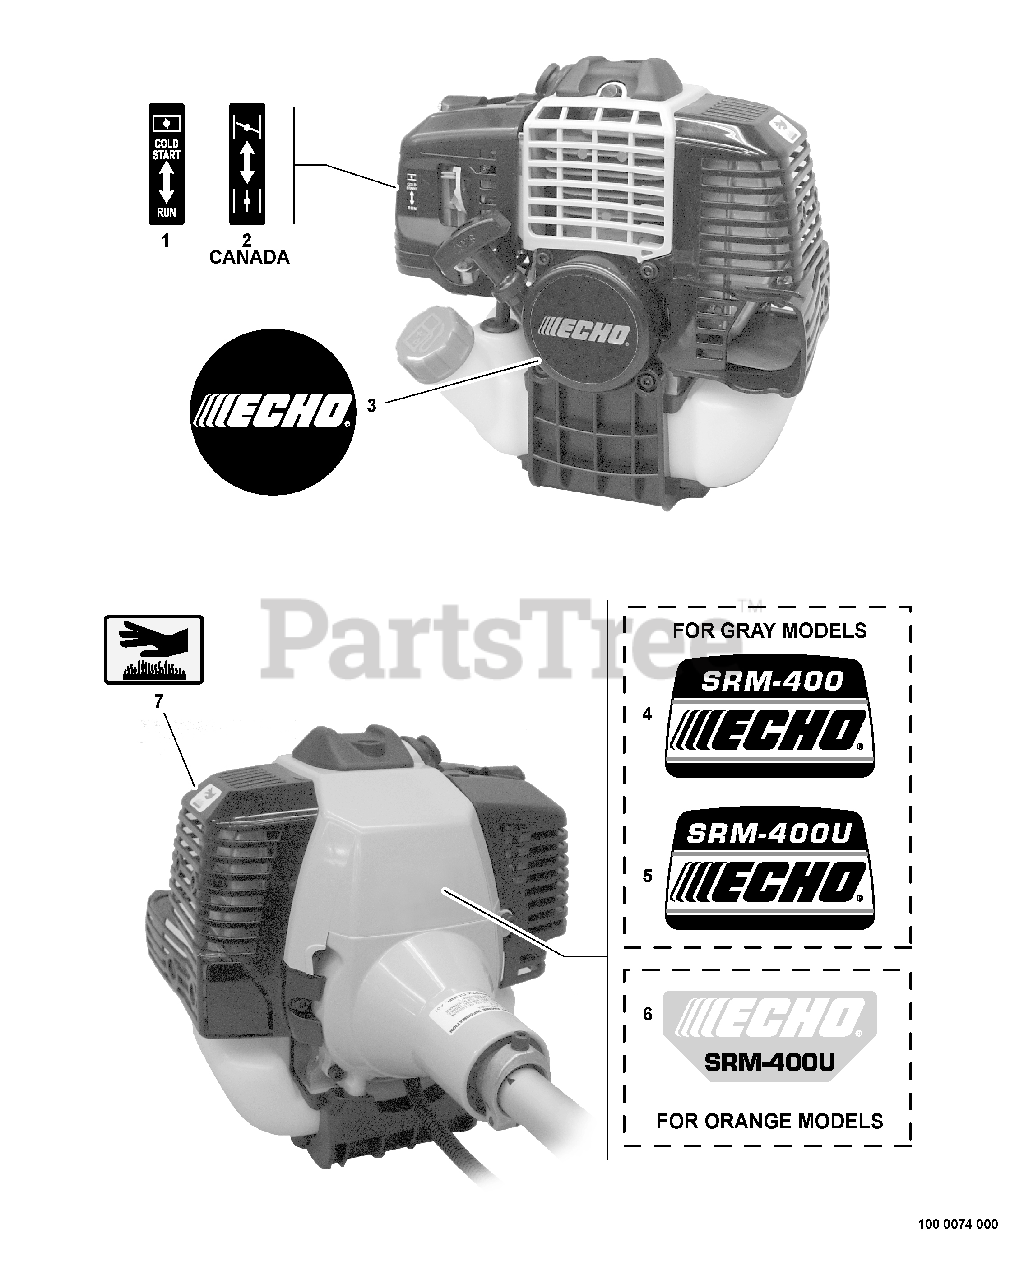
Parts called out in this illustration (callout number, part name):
1	LABEL - CHOKE
2	LABEL - CHOKE
3	LABEL - ECHO
4	LABEL - MODEL SRM-400
5	LABEL - MODEL SRM-400U
6	LABEL - MODEL SRM-400U
7	LABEL - HOT SURFACE
